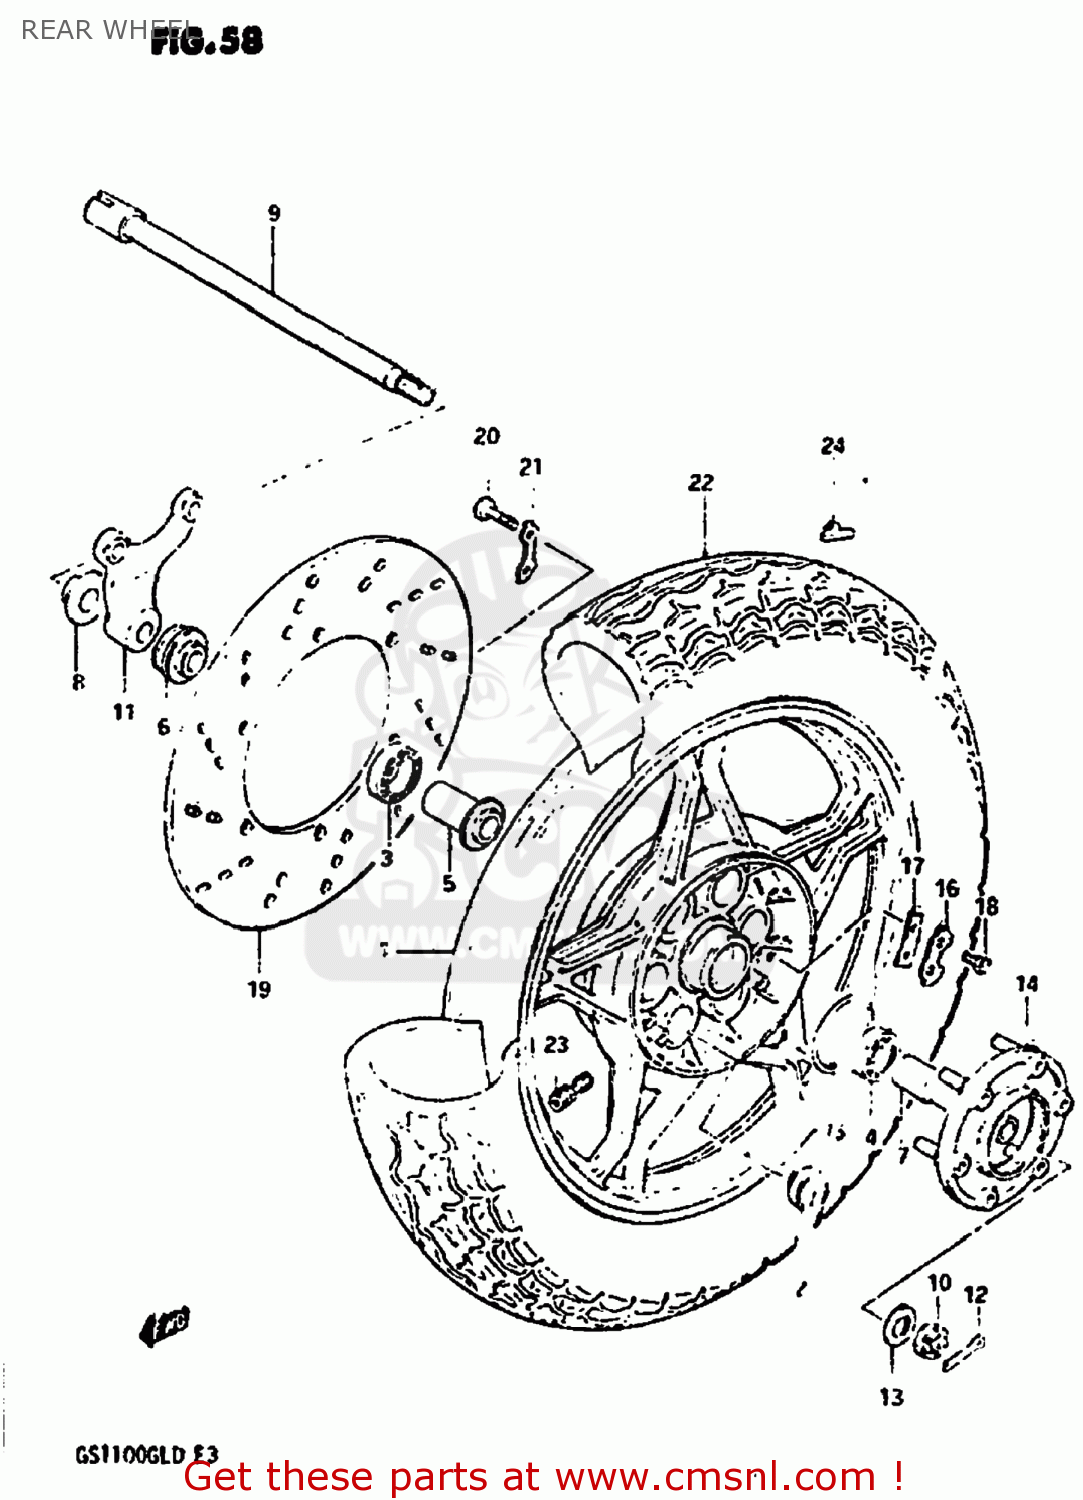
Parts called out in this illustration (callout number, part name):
1	CASTING WHEEL,REAR
2	BUSH
3	BEARING
4	BEARING
5	SPACER,REAR HUB BEARING
6	SPACER,REAR AXLE
7	SPACER,REAR AXLE,LEFT
8	SPACER,REAR AXLE,RIGHT
9	AXLE,REAR
10	NUT
11	BRACKET,RR,CALIPER
12	PIN,COTTER
13	WASHER (17.5X36X3.2)
14	JOINT ASSEMBLY,REAR HUB DRUM
15	O RING(D:2.1,ID:65)
16	WASHER
17	WASHER,THRUST(T:1.6)
18	SCREW
19	DISC,RR BRAKE
20	BOLT(8X25)
21	WASHER
22	TIRE
23	VALVE ASSEMBLY,WHEEL RIM,J
24	BALANCER,WHEEL
